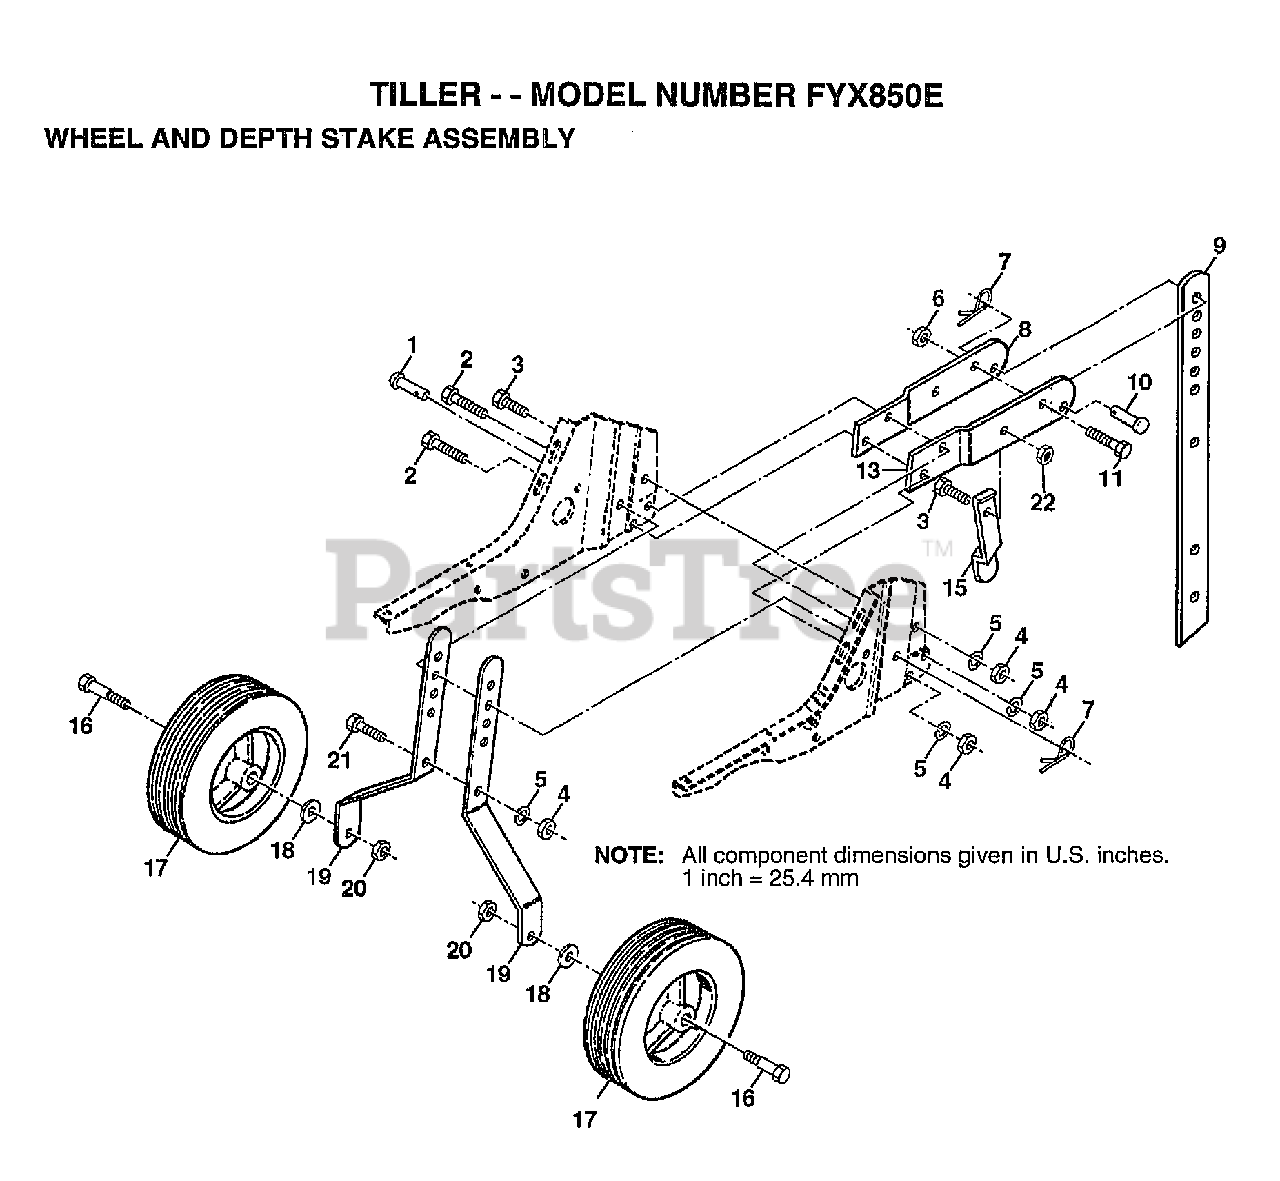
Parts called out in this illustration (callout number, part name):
1	DRILLED RIVET RT
3	BOLT
4	NUT.HEX.5/16-18
5	LOCKWASHER
6	NUT
7	SPRING.RETAINER
11	BOLT
15	STAKE SPRING TI
16	BOLT SHOULDER
18	WASHER
22	NUT
